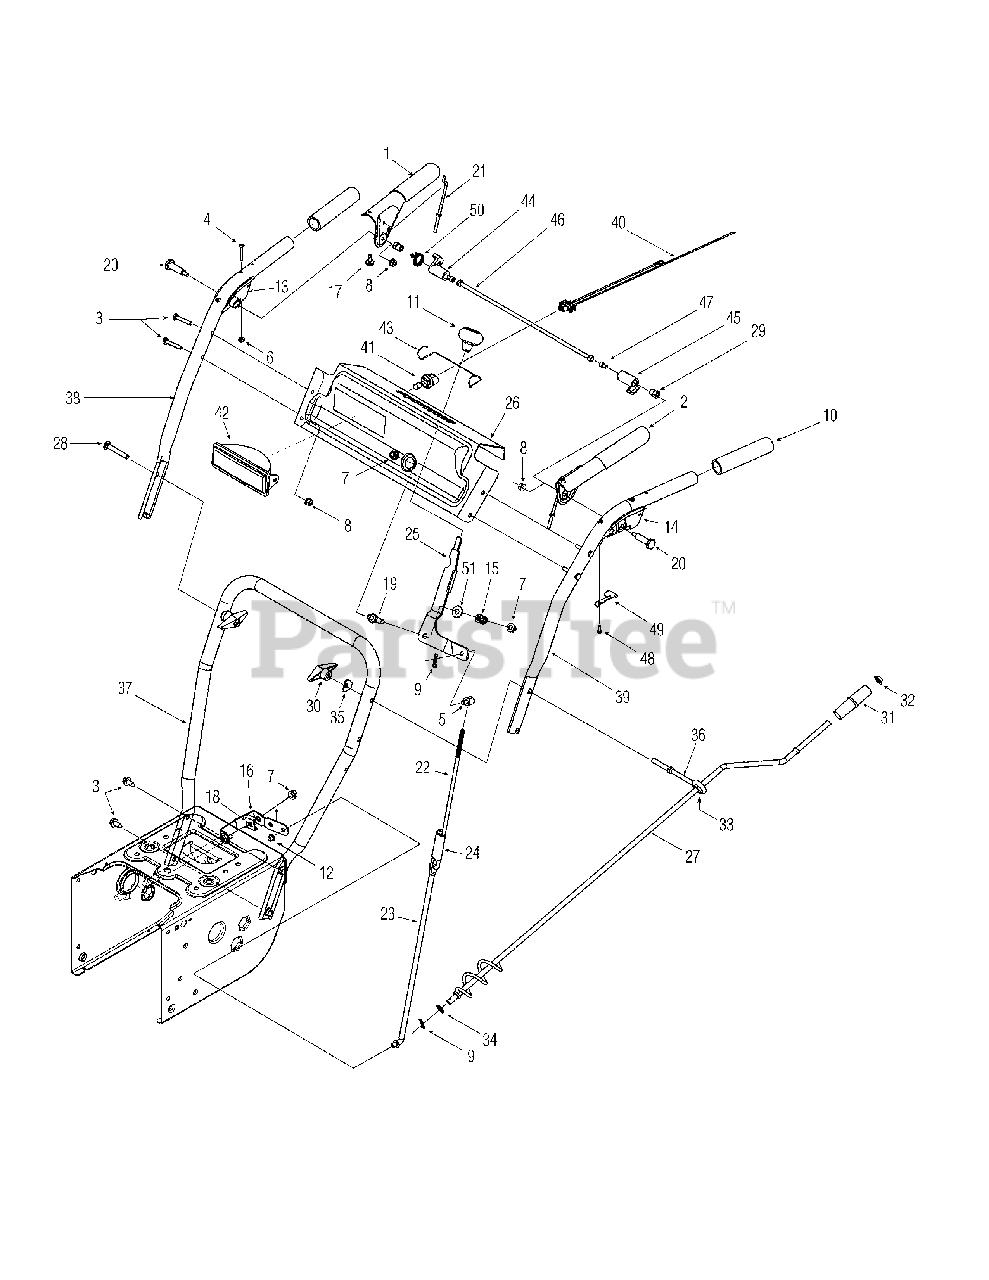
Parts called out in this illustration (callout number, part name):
1	Handle Ass’y, Engagement RH Black
2	Handle Ass’y, Engagement, LH Black
3	Screw, Self-tapping, 5/16-12, 0.750
4	Screw, Machine, #10-24, 1.375
5	Ferrule, 5/16-18 x .312 Diameter
6	Nut, Hex Lock, #10-24, Gr2, Nylon
7	Nut, Flange Lock, 5/16-18, Grf, Nylon
8	Nut, Flange Lock, 1/4-20, Grf, Nylon
9	Pin, Cotter, .072 Diameter x 1.13
10	Grip, 1.0 ID x 5.0
11	Shift Knob, Black
12	Nut, Push, 5/16
13	Handle, Clutch Lock, RH
14	Handle, Clutch Lock, LH
15	Spring, Compression, .39x.60 x .88
16	Spring, Shift, Lever
17	Bumper, Rubber, .62 OD x .22
18	Bracket, Shift Spacer
19	Bolt, Shoulder, 5/16-18 x 0.830
20	Screw, Shoulder, .437 x 1.345, 1/4-20
21	Z Fitting, Cable
22	Rod, Shift, .312 x 11.5 Upper
23	Rod, Shift, Lower
24	Connector Sleeve, Shift Rod
25	Lever, Shift, Speed
27	Crank Assembly, Chute
28	Screw, Carriage, 5/16-18, 2.25, Gr5
29	Shoulder Nut, Hex, 1/4-20
30	Knob Assembly, Wing Nut, 5/16-18
31	Crank Knob, 1.0 Diameter x 3.2, Black
32	Cap, Push, 3/8 Rod
33	Grommet, .44 ID x .94 OD x .50
34	Washer, Flat, .375 x .738 x .063
35	Washer, Saddle, 320 x .93 x .060
36	Eye Bolt, Chute Crank
40	Harness, Headlight
41	Lamp, Halogen, 12V, 27W
42	Lens Assembly, Lamp
43	Retainer, Lens
44	Plate, Lock
45	Cam, Lock
46	Rod, Pivot
47	Screw, 1/4-20, .375
48	Screw, #8-18 x .50
49	Spring, Control Lever Lock
50	Spring, Torsion, .8156 x .3038
51	Washer, Flat, .385 x .870 x .092
